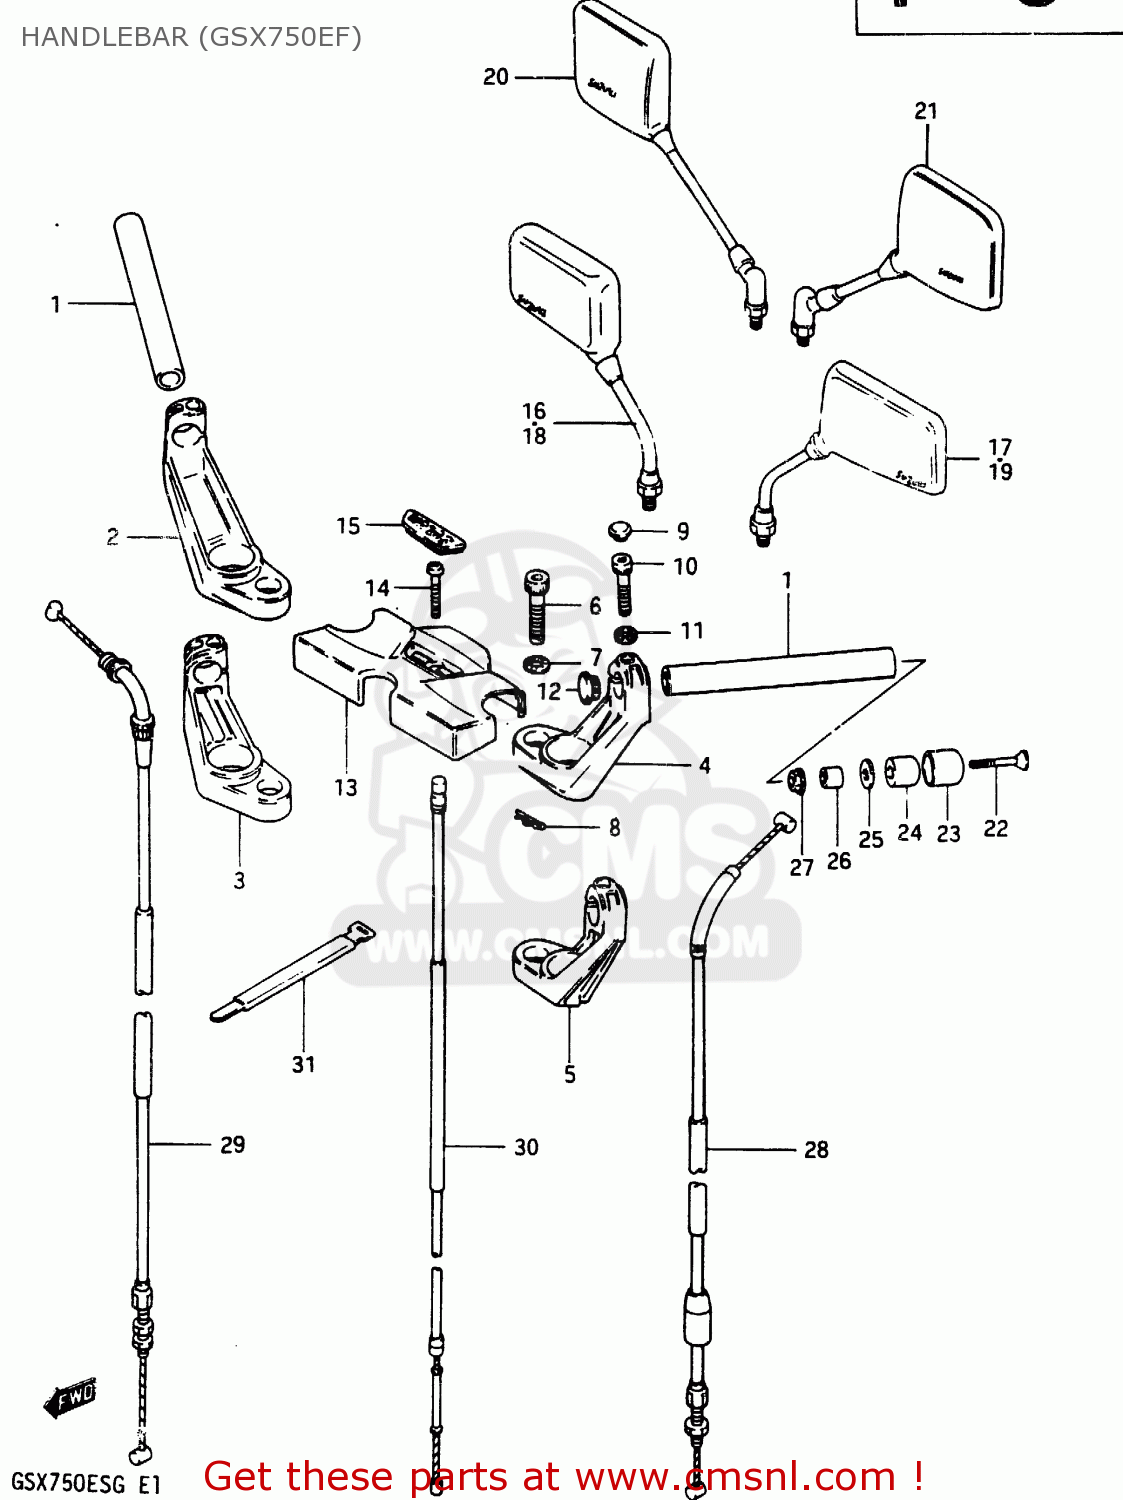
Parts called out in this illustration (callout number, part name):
1	HANDLEBAR
2	HOLDER,HANDLEBAR,RIGHT
3	HOLDER,HANDLEBAR,RIGHT
4	HOLDER,HANDLEBAR,LEFT
5	HOLDER,HANDLEBAR,LEFT
6	BOLT 10X50
7	WASHER
8	CLIP
9	CAP(OD:14.5)
10	BOLT 8X35
11	WASHER
12	CAP,GRIP END
13	PAD,HANDLE
14	SCREW
15	CAP,HANDLE PAD
16	MIRROR ASSEMBLY,RIGHT
17	MIRROR ASSEMBLY,REAR VIEW
18	MIRROR, REAR VIEW RH
19	MIRROR, REAR VIEW LH
20	MIRROR ASSEMBLY,REAR VIEW
21	MIRROR ASSEMBLY,REAR VIEW
22	SCREW 6X65
23	CAP,BALANCER
24	BALANCER,HANDLE
25	SPACER,BALANCER
26	EXPANDER,BALANCER
27	NUT
28	CABLE ASSY,CLUTCH
29	CABLE ASSY,THROTTLE
30	CABLE COMP,STARTER
31	CLAMP
